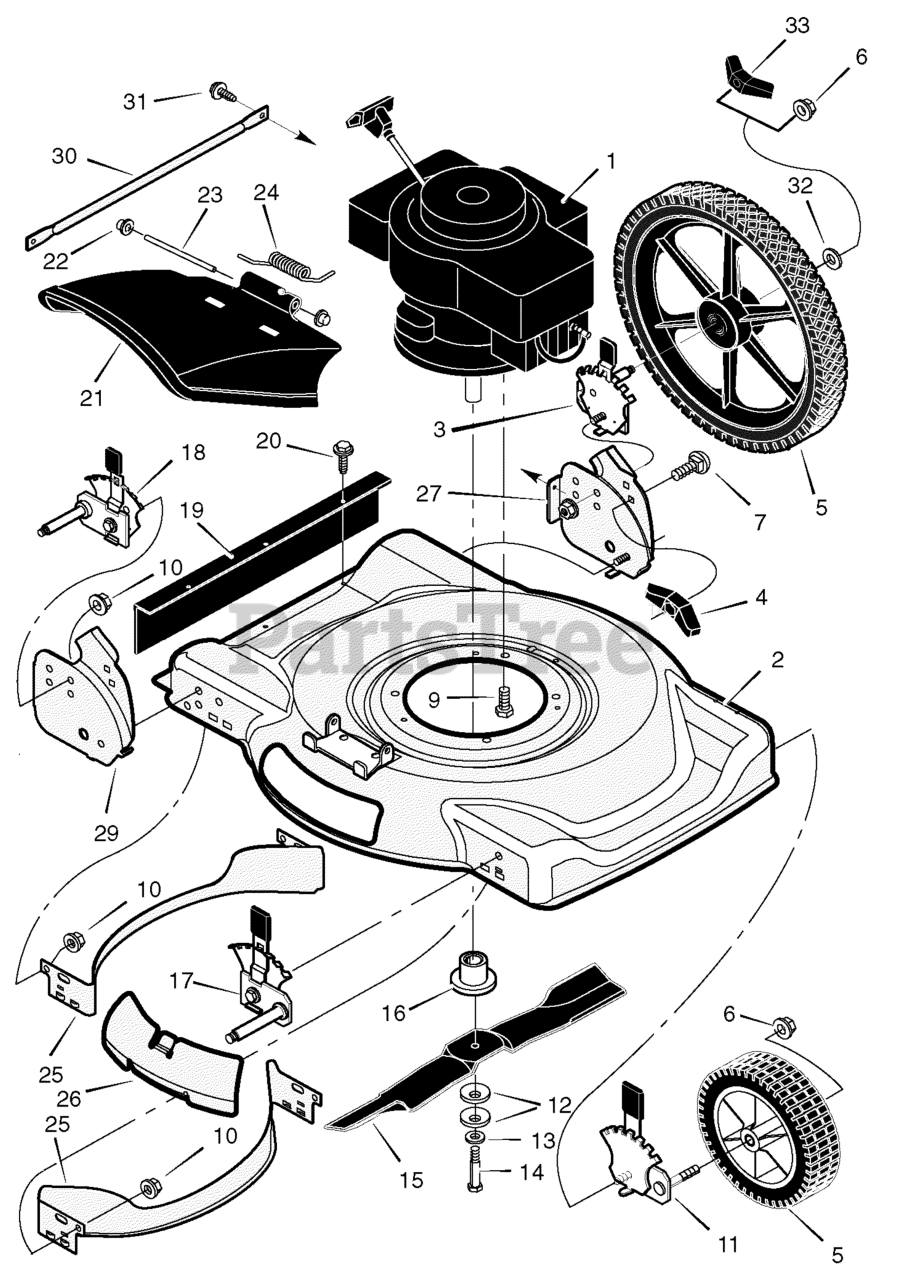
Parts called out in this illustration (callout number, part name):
1	Engine
2	Housing
3	Height Adjuster, Left Rear
5	Wheel and Tire
6	Locknut, Flange
7	Bolt, Carriage
9	Bolt, Engine
10	Nut
11	Height Adjuster, Left Front
12	Washer, Belleville
13	Washer
14	Bolt, Hex
16	Adapter, Blade
17	Height Adjuster, Right Front
18	Height Adjuster, Right Rear
19	Guard, Rear
21	Deflector, Chute
22	Push-On Cap
23	Pin, Pivot
24	Spring
26	Plate, Mulcher
27	Bracket, Left Handle
29	Bracket, Right Handle
31	Screw
33	Knob, Axle
